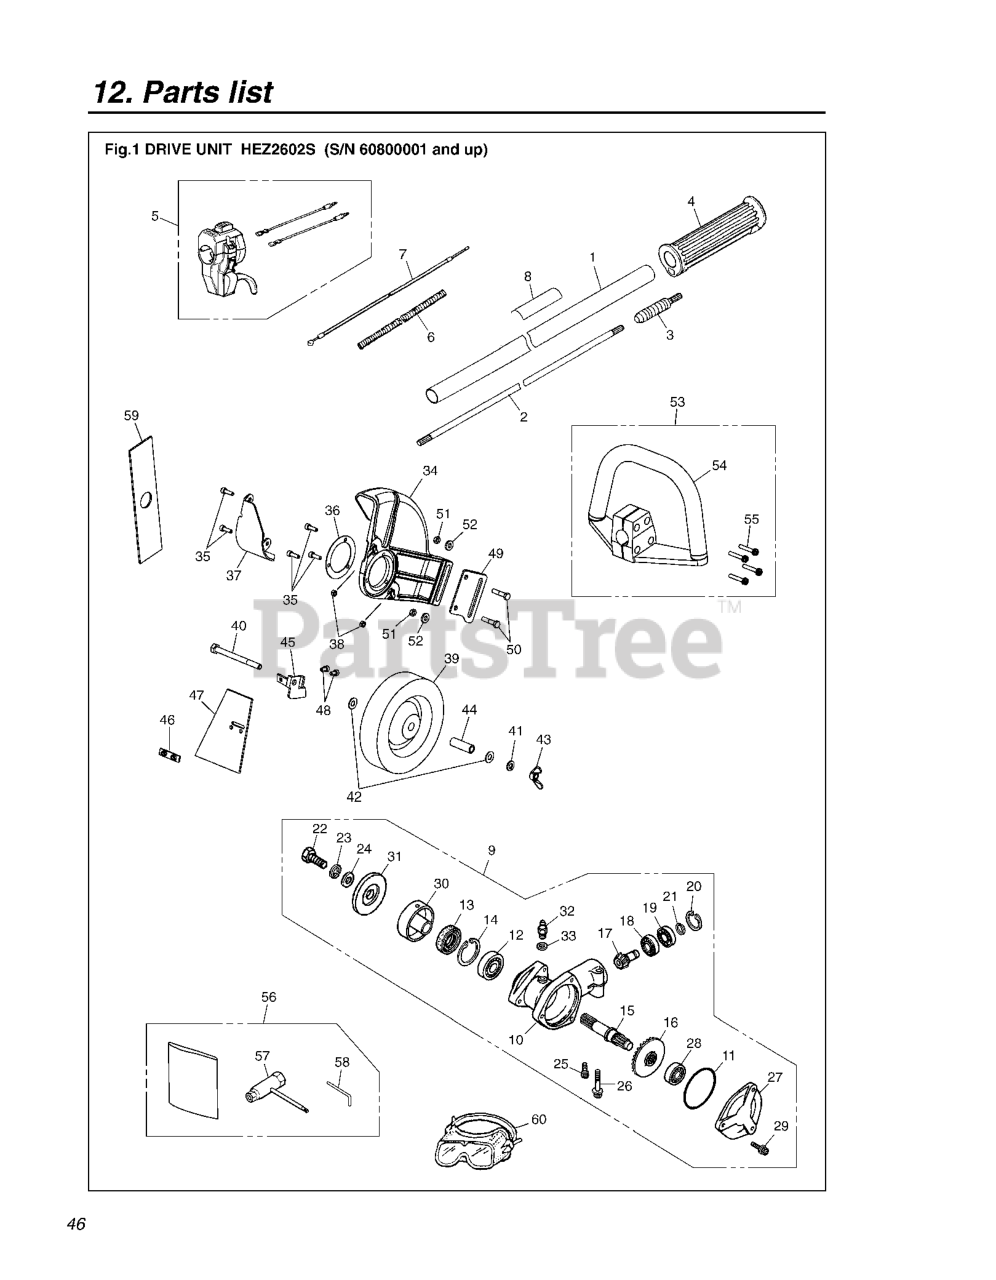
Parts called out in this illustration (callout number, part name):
1	PIPE COMP (RPLS 848A475820)
2	DRIVE SHAFT (BCZ2601S)
3	JOINT COMP
5	LEVER COMP (RPLS 8488R20343)
9	GEARCASE ASSY
10	GEARCASE
13	OIL SEAL
22	BOLT M8 X L25 L/H
25	BOLT, M5 x 12
29	BOLT M5 X L14 ALLEN
30	HOLDER(A)
31	HOLDER (B)
34	GUARD
35	BOLT M5 X L16 ALLEN
37	PROTECTOR
40	BOLT M8 X L65
43	RP_NUT
48	BOLT M5 X L10 ALLEN BOLT
49	MAIN BRACKET
50	BOLT M8 X L40
53	HANDLE ASSY. (RPLS T319514001)
54	HANDLE T
56	TOOL SET
60	GOGGLExxx (RPLS
